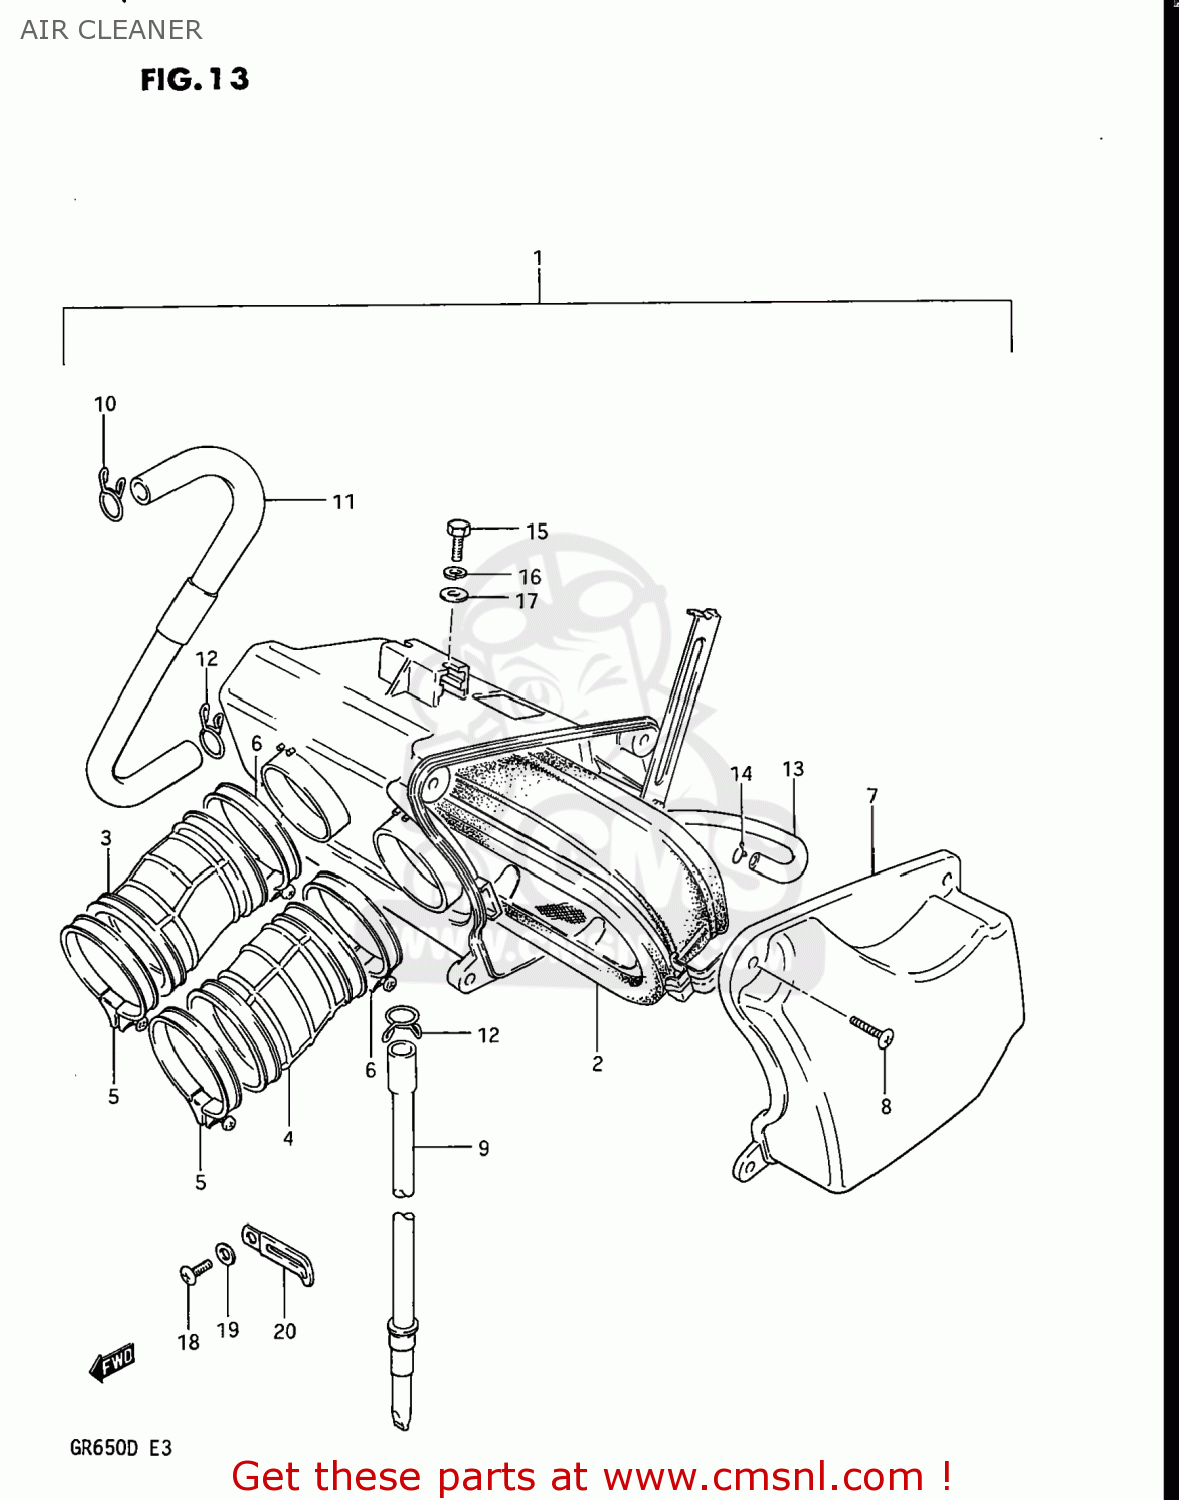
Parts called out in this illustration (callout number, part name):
1	CLEANER ASSEMBLY,AIR
2	FILTER,AIR CLEANER
3	TUBE,AIR CLEANER OUTLET
4	TUBE,AIR CLEANER OUTLET
5	CLAMP
6	CLAMP
7	CAP,AIR CLEANER
8	SCREW
9	DRAIN TUBE
10	CLIP,BREATHER TUBE
11	TUBE,BREATHER
12	CLIP,BREATHER TUBE
13	HOSE, BREATHER (L:300)
14	CLIP
15	BOLT, UPPER
16	LOCK WASHER
17	WASHER
18	SCREW
19	WASHER
20	CLAMP
